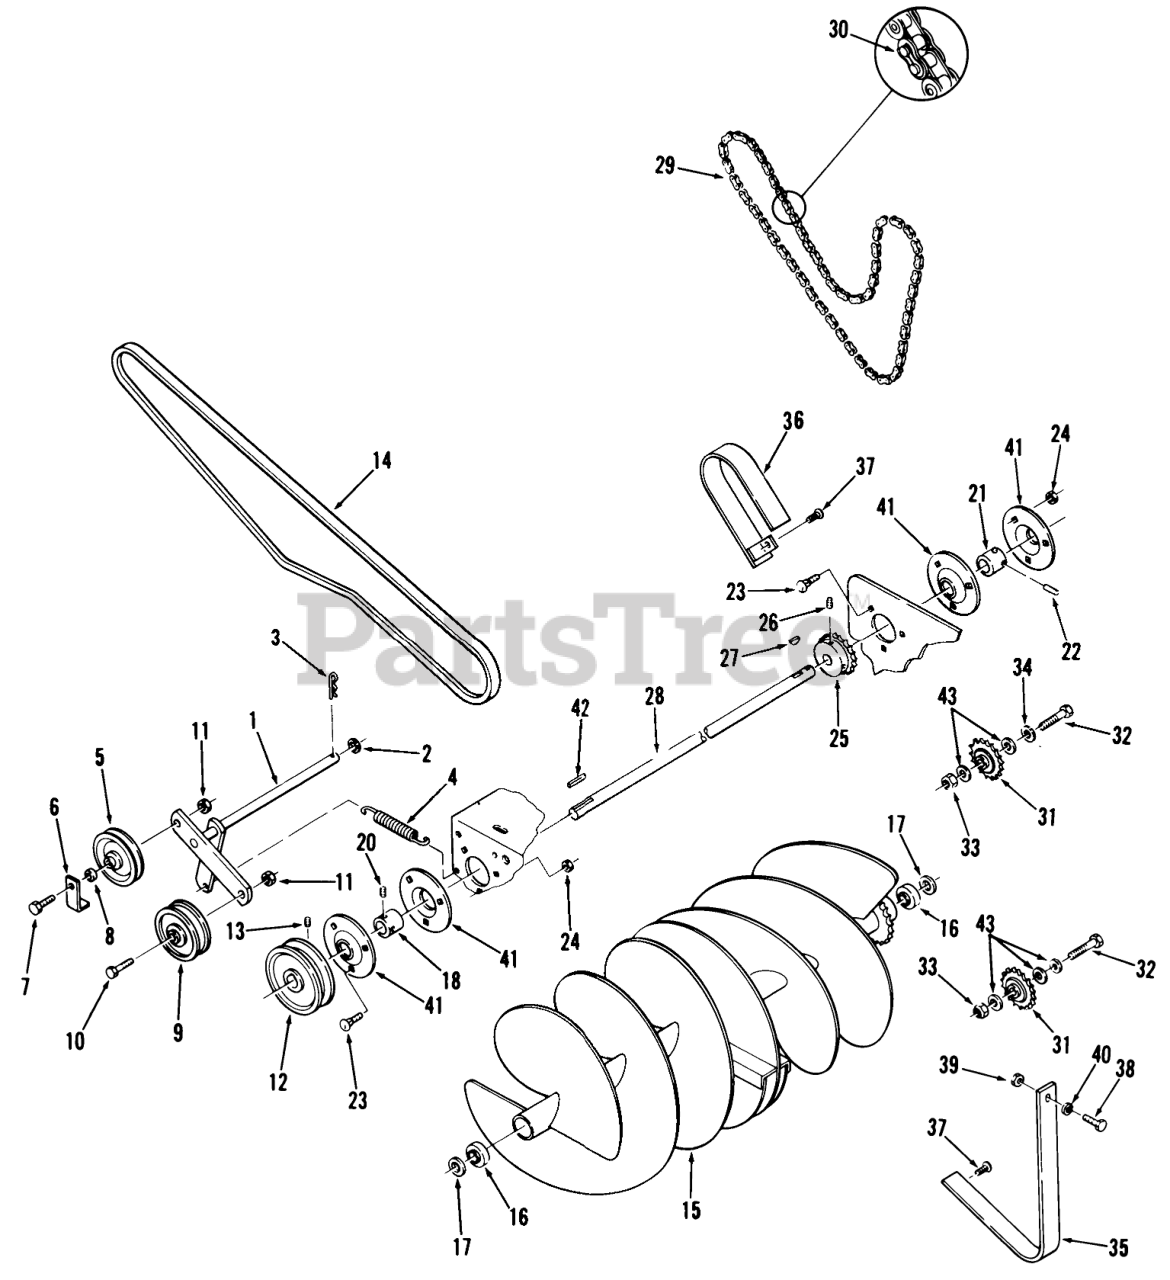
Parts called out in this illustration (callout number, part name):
1	ASSY IDLER ARM R
2	Washer
3	Hairpin
3	Nut
4	SPRING R
5	PULLEY-IDLER
6	Spacer
7	Bolt
8	SPACER
9	Idler Pulley
10	BOLT
11	Nut
12	Pulley
13	Set Screw
14	V-BELT
15	Auger
16	BEARING-BALL
17	Washer
18	BALL BEARING
20	SET SCREW
21	LUTCO BALL BEARING
22	PIN-ROLL, SPIROL
23	Bolt
24	Nut
25	SPROCKET
26	SCREW-SET
27	Key
28	SHAFT
29	CHAIN
30	MASTER LINK CHAIN
31	Idler Sprocket
32	H H C S
33	Eslok Nut
34	SPACER
35	Guard-Inner
36	Guard-Outer
37	SCREW
38	H H C S
39	Nut 1/4-20
40	WASHER
41	FLANGE
42	KEY-STRAIGHT
43	Washer
